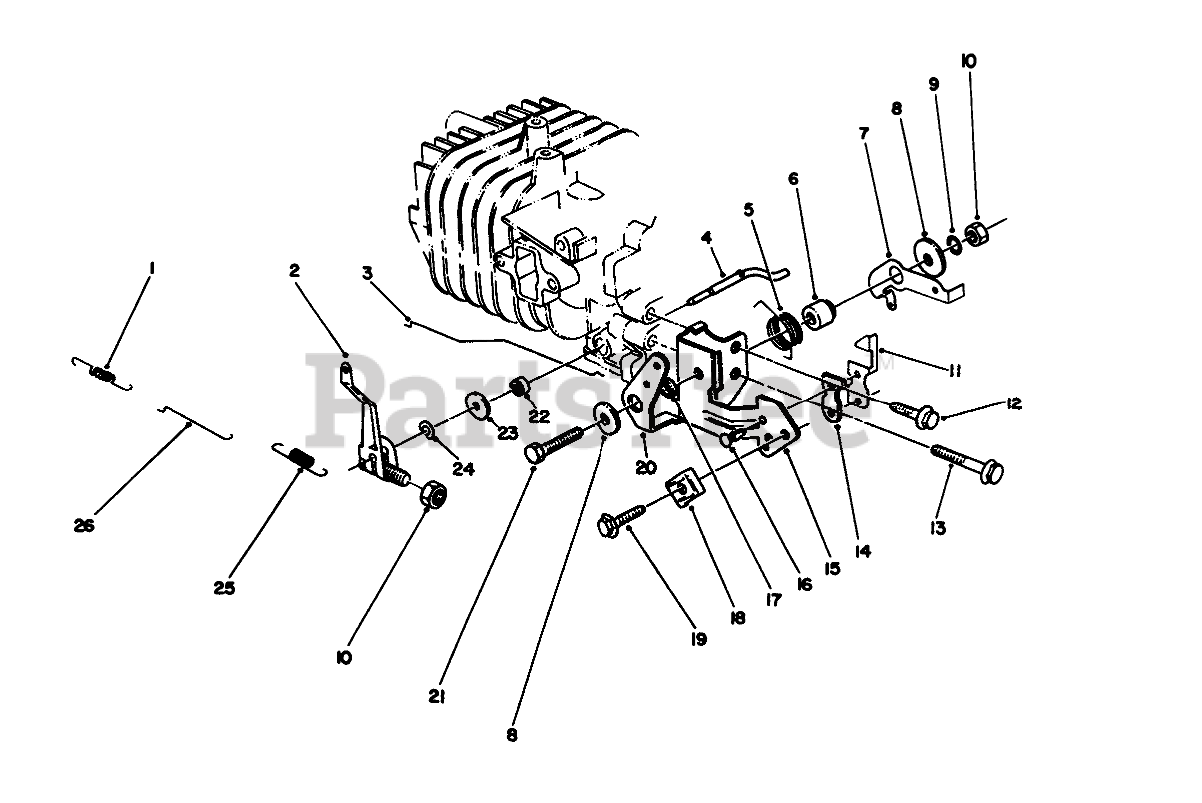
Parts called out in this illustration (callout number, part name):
1	SPRING
2	ARM-GOVERNOR
3	ROD-CHOKE
4	SHAFT
5	SPRING-CHOKE LEVER
6	SPACER
7	LEVER-SPRING, GOVERNOR
8	WASHER
9	LOCKWASHER
11	TERMINAL-KILL SWITCH
14	INSULATOR-KILL SWITCH
15	BRACKET
16	RIVET
17	SPACER-CHOKE LEVER
18	CLAMP
20	LEVER-CONTROL, CHOKE
22	SEAL-OIL
23	WASHER
24	E-RING
25	SPRING-GOVERNOR
26	ROD-CARBURETOR
